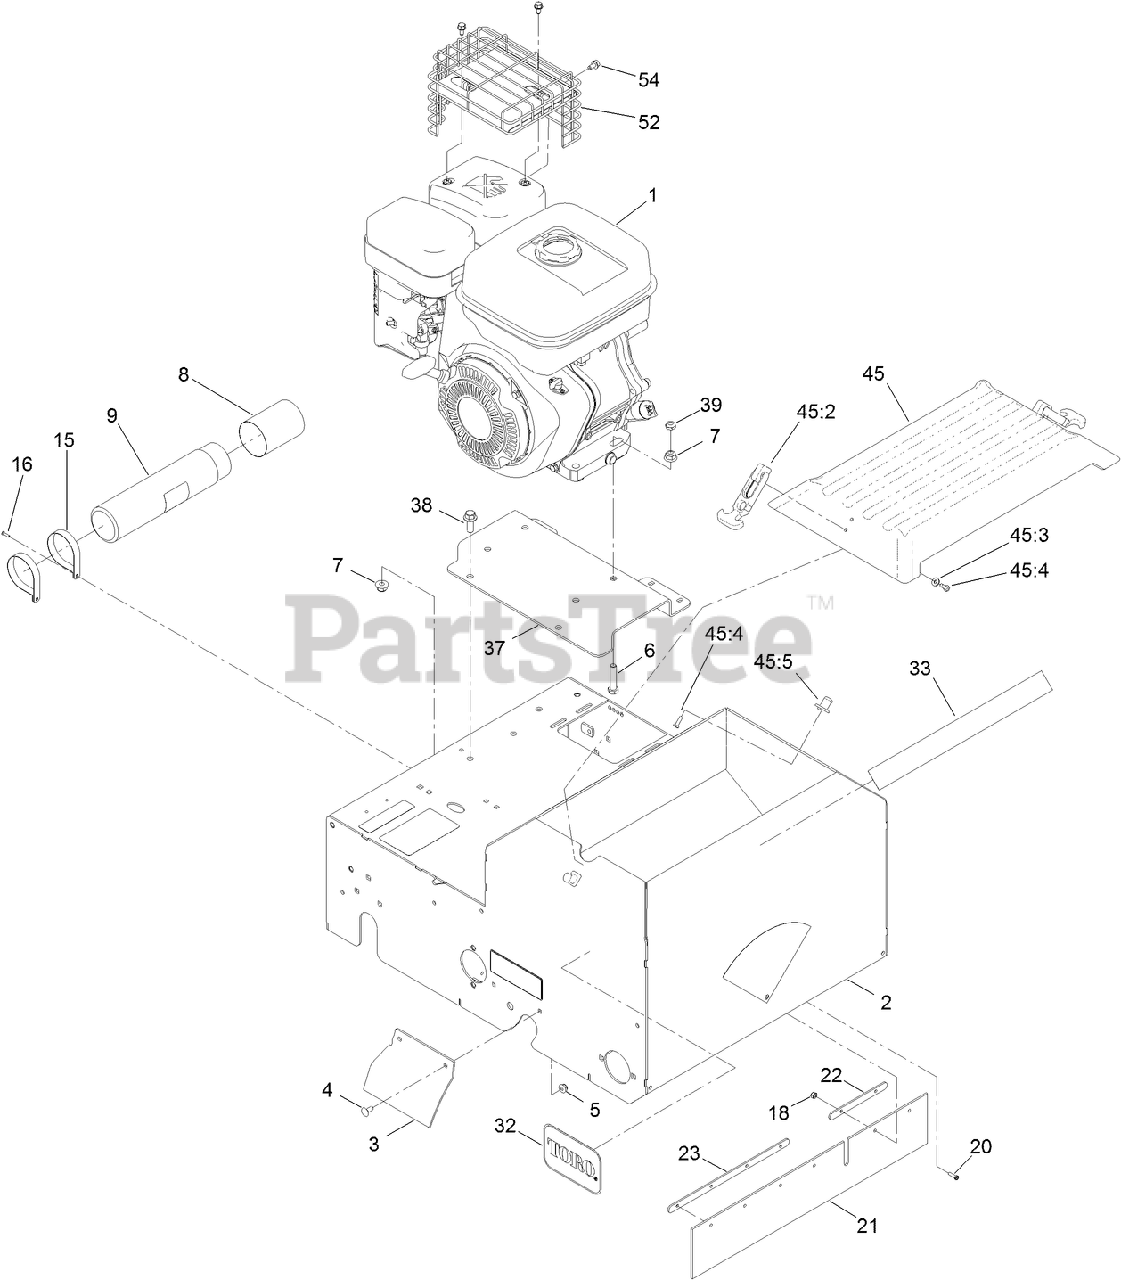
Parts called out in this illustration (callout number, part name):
2	FRAME ASM
3	GUARD-RH
4	SCREW-CARR
5	NUT-HF
6	SCREW-HH
7	NUT-HF, NI
8	CAP-HOUSING
9	TUBE-MANUAL
15	CLAMP-R
16	RIVET-POP
18	NUT-LOCK
20	SCREW-SHH
21	GUARD-DUST
22	PLATE-RETAINER
23	PLATE-RETAINER
32	DECAL
37	PLATE-ENGINE
38	SCREW-HHF
39	NUT-LOCK, NI
45	SEEDER COVER KIT
45:2	LATCH-RUBBER
45:3	WASHER-FLAT
45:4	SCREW-PPH
45:5	LATCH-KEEPER
52	GUARD, MUFFLER
54	SCREW-HWH
